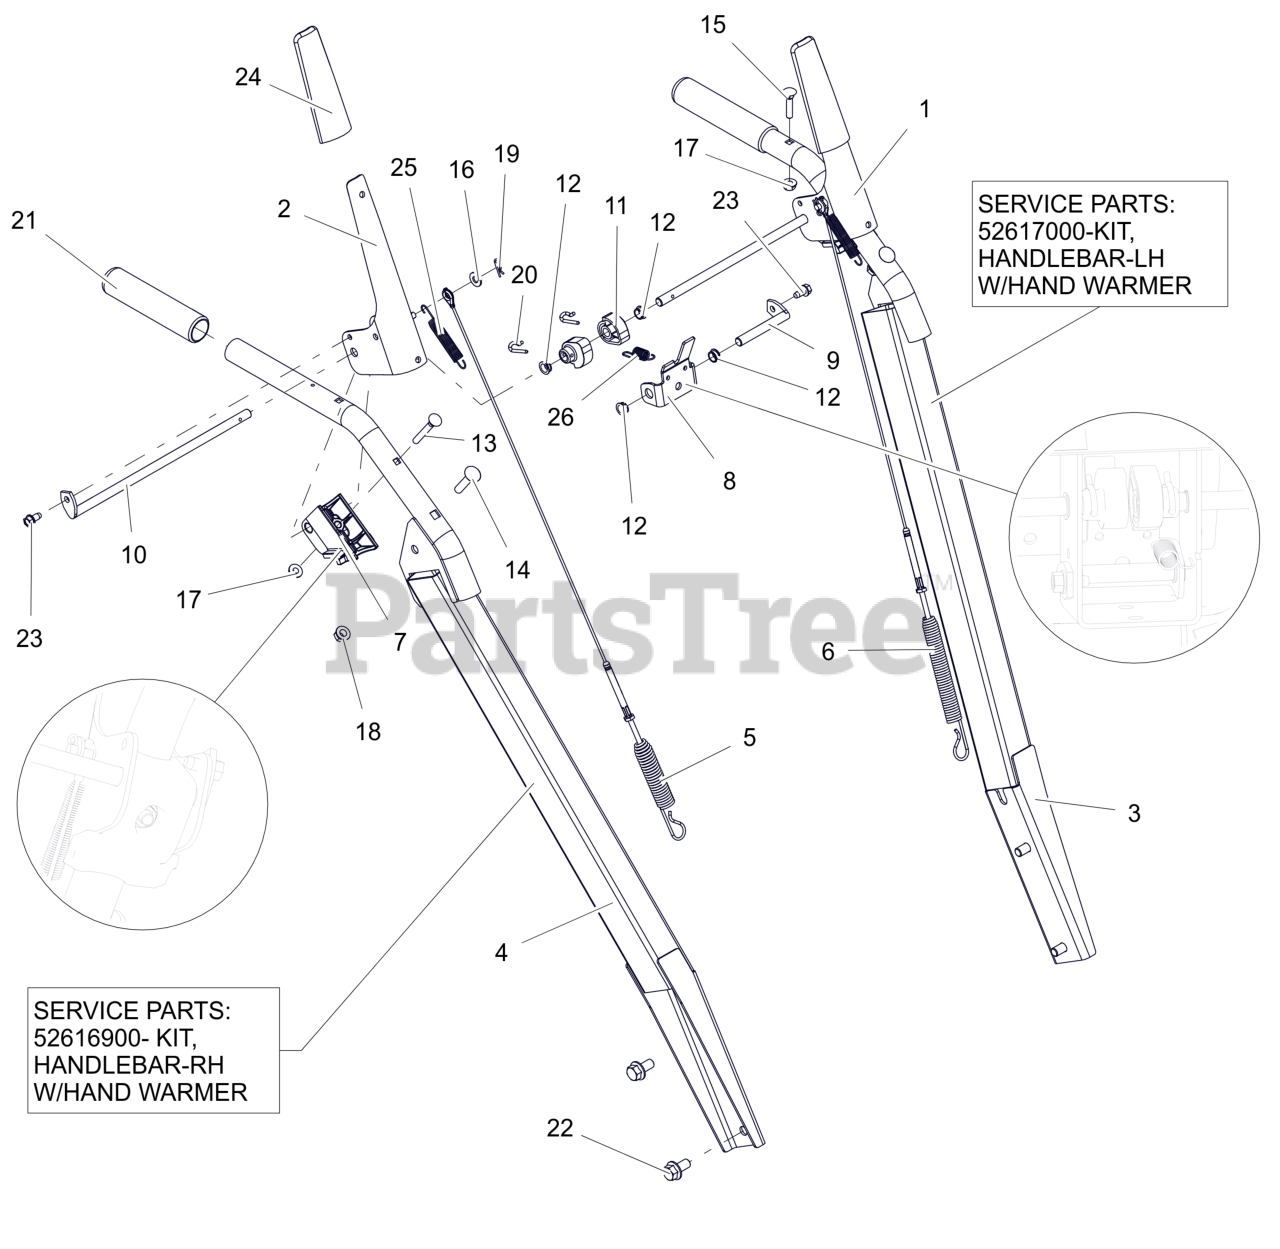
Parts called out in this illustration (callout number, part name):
1	LEVER, CLUTCH-LH
1	KIT, HANDLEBAR-LH W/WARM GRIP
2	LEVER, CLUTCH-RH
2	KIT, HANDLEBAR-RH W/WARM GRIP
3	HANDLEBAR, HEAVYDUTY-PRO LH
4	HANDLEBAR, HEAVYDUTY-PRO-RH
5	CABLE, AUGER (DELUXE & PRO)
6	CABLE, UPPER TRACTION
7	BLOCK, CLUTCH PADDLE
8	BRACKET, INTERLOCK ARM
9	ROD, PIVOT - INTERLOCK
10	ROD, PADDLE MOUNT - PRO
11	CAM, INTERLOCK
12	BUSHING, POLYLINER-.38 SNAPIN
13	BLT-RDHDXLSQNK .25-20X2.0 G5YZ
14	BLT,RHSN .31-18X1.50 G5 ZCC
15	BLT-RDHDXLSQNK.25-20X1.25 G5ZC
16	WSHR,FLT .281X.625X.065 ZCC
17	NUT-LK-CTR-FLG .25-20 ZC120
18	NUT-LK-TOP-FLG .312-18 GF ZCC
19	PIN, HAIR #178 .06X.77 ZCC
20	PIN, SPRING CLIP
21	GRIP, HANDLEBAR
23	SCR-TAP .25-20X.50 HWH ZCC
24	COVER, PADDLE
25	SPRING, EXTENSION
26	SPRING-EXT .047X.438X1.45
